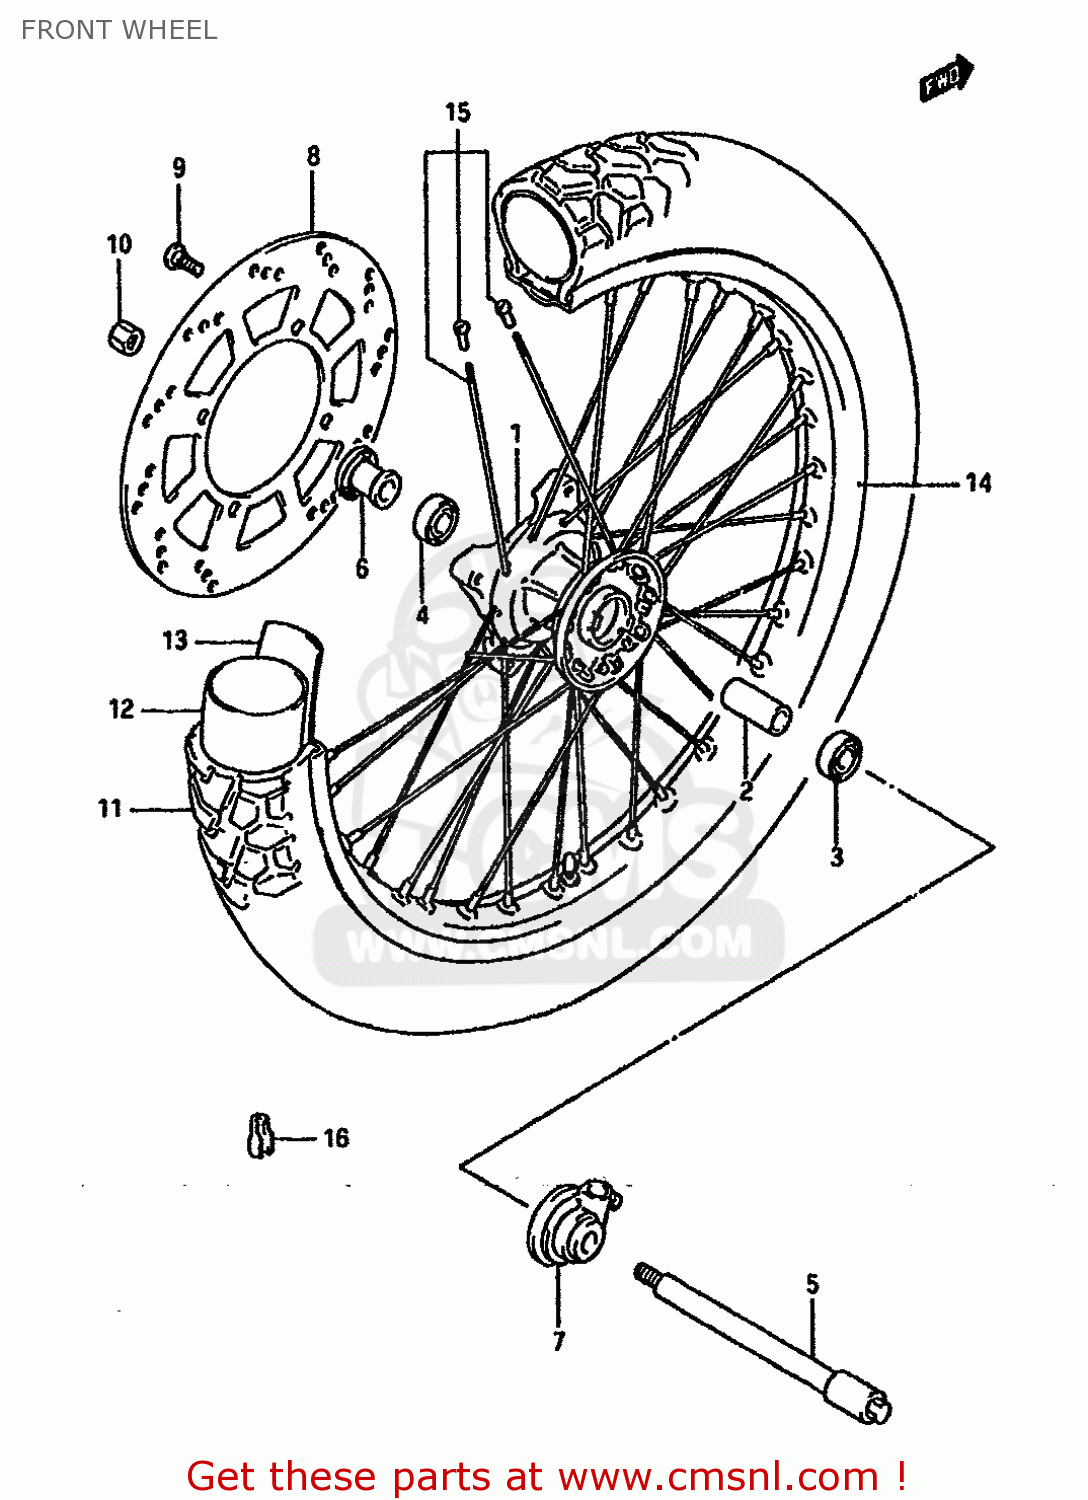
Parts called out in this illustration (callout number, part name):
1	HUB,FRONT WHEEL
2	SPACER,FR HUB BEARING
3	BEARING(15X32X15.9)
4	BEARING
5	AXLE,FR
6	SPACER,FRONT AXLE,LEFT
7	BOX ASSEMBLY,SPEEDOMETER GEAR
8	DISC,FR BRAKE
9	BOLT,BRAKE DISC
10	NUT
11	TIRE,FRONT (90/90-21) 54S
12	TUBE,INNER
13	PROTECTOR,WHEEL,INNER
14	RIM,FR WHEEL(21X1.85)
15	SPOKE SET,FR WHEEL
16	BALANCER,WHEEL
